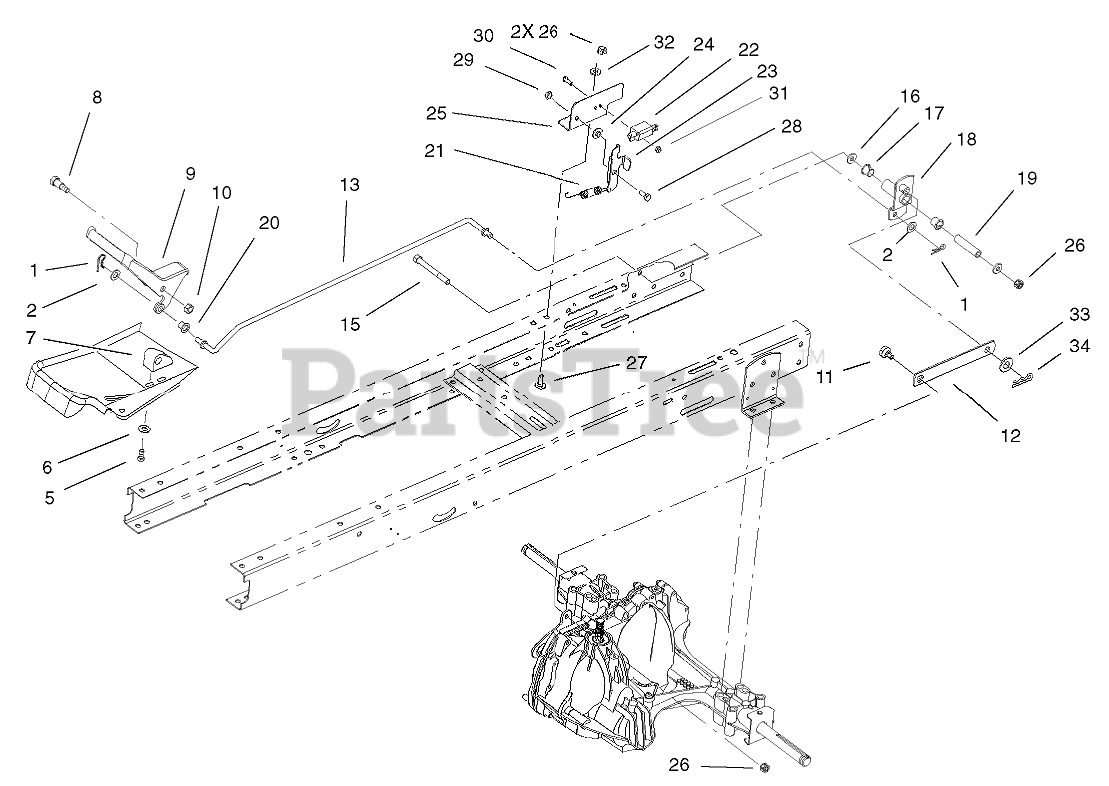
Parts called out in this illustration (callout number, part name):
1	PIN-COTTER
2	WASHER-FLAT
5	SCREW-PLASTITE
6	WASHER-FLAT
7	BLOCK-PIVOT
8	SCREW-SHOULDER, HH
9	PEDAL-CONTROL, SPEED
10	NUT-LOCK, NI
11	BOLT-SHOULDER
12	LINK-CONTROL, SPEED
13	ROD-CONTROL, SPEED
15	SCREW-HH
16	WASHER-FLAT
17	BUSHING-NYLINER
18	PIVOT ASM
19	SPACER-PIVOT
20	BUSHING-FLANGED
21	SPRING-EXTENSION
22	SWITCH-POLE, SINGLE
23	BRACKET-PIVOT
24	WASHER-STEPPED
25	BRACKET-ADJUSTMENT
26	NUT-LOCK, NI
27	SCREW-CARR
28	SCREW-HHF
29	NUT-LOCK, NI
30	SCREW-SHH
31	NUT-LOCK
32	WASHER-PLAIN
33	WASHER-FLAT
34	PIN-HAIR
